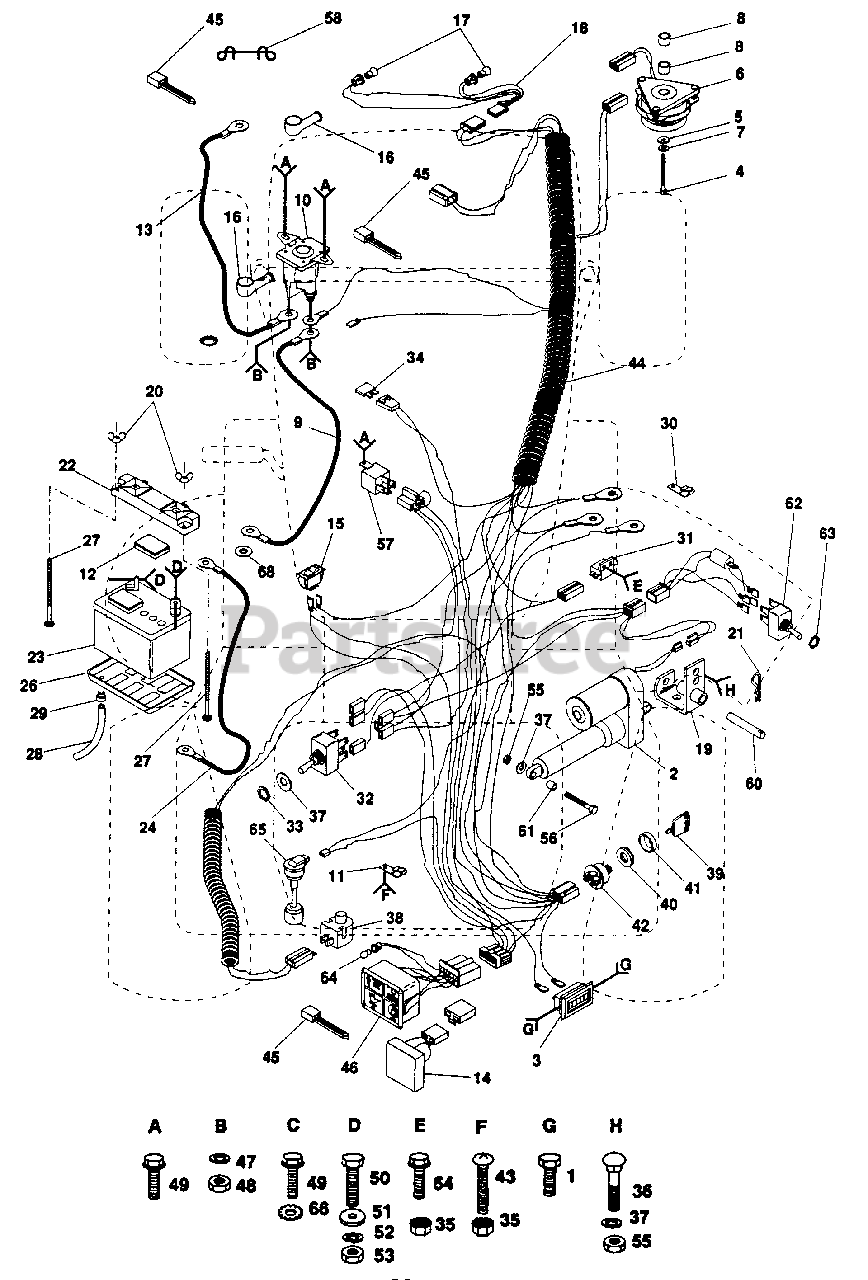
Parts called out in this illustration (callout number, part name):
1	Screw #10-24 x 1/2
2	Actuator, Electric
3	Meter, Hour
4	Bolt, Hex 7/16-20 x 1-1/2 Gr. 8
6	Clutch, Electric
7	Washer, Lock 7/16
8	Spacer, Clutch
9	Cable, Battery
10	Solenoid
11	Clip, Insulated
12	Battery Caps
13	Cable, Starter
14	Sensor, Low Voltage
15	Switch, Light
16	Cover, Terminal
17	Bulb, Light
18	Harness, Light Socket
19	Bracket Assembly, Actuator
20	Nut, Wing 1/4-20
21	Spring, Retainer
22	Guard Terminal
23	Battery
24	Cable Ground
26	Tray, Battery
27	Bolt, Carriage 1/4-20 x 7-1/2
28	Tube, Plastic
29	Clamp, Hose
31	Switch, Interlock
32	Switch, P.T.O.
33	Nut, Hex
35	Nut, Keps #10-32
36	Bolt, Carriage 3/8-16 x 1
37	Washer, Lock 3/8
38	Switch, Seat
40	Nut, Ignition
41	Bezel, Ignition
42	Switch, Ignition
43	Screw, Slot, Pan HD #10-32 x 1/2
44	Harness, Ignition
45	Cable Tie
46	Light Package
47	Washer, Lock 1/4
48	Nut, Hex Jam 1/4-20
49	Screw, Hex Washer Hd. Cutting 1/4-20 x 1/2
50	Bolt, Hex Hd. 1/4-20 x 3/4
51	Washer 9/32 x 5/8 x 16 Gauge
52	Washer, Lock 1/4
53	Nut, Hex 1/4-20
54	Screw, Hex Washer Hd. #10-32 x 1-1/2
55	Nut, Fin Hex 3/8-16
56	Bolt, Fin Hex 3/8-16 x 2-1/4
57	Assembly, Relay
60	Pin, Actuator
62	Switch Assembly, Lift
63	Washer, Lock
64	Bulb, Dashboard, Light
65	Sensor, Low Fuel
66	Washer, Lock, External Tooth
67	Washer 17/32 x 3/4 x 16 Ga.
68	Washer, Lock, Int. tooth 1/4
